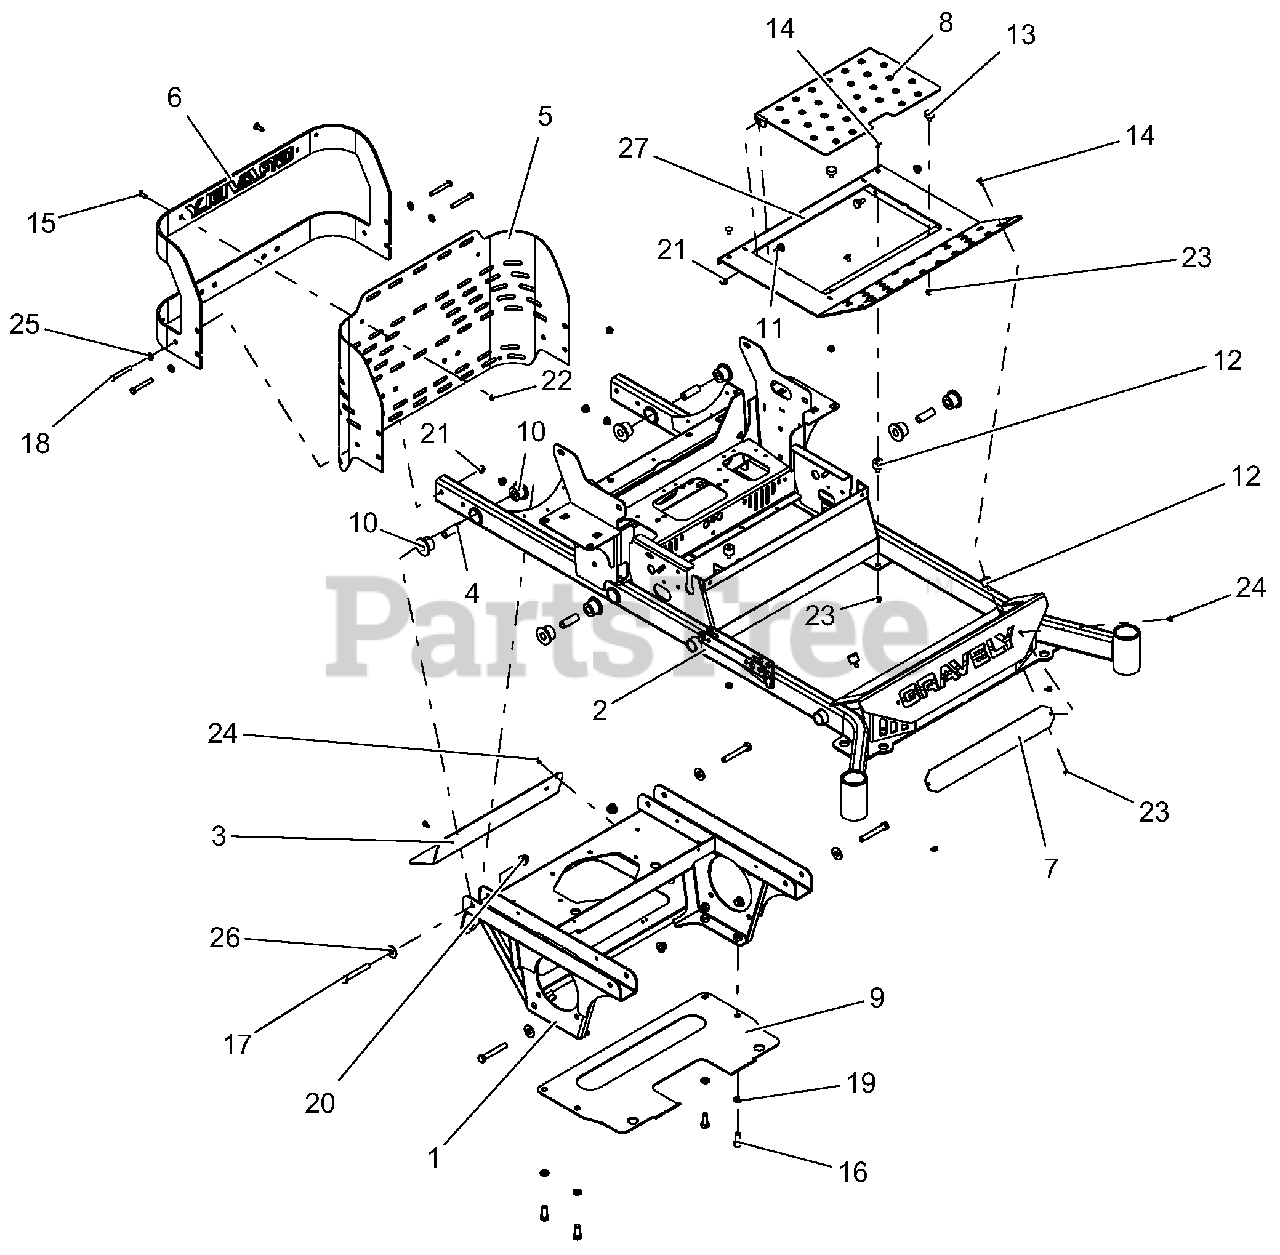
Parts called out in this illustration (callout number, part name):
1	WLDT, 200 PT AXLE/ENGINE FRAME
2	52-66" MAIN FRAME W/SAFETY DECALS
3	SHIELD, MUFFLER HEAT-BLACK
4	SPCR, .50 X .75 X 2.23 YZ
5	GUARD, REAR BUMPER FINGER-BLACK
6	REAR BUMPER W/SAFETY DECALS-GAS
7	PLATE, BUMPER LOGO BACKING-BLACK
8	INSPECTION PANEL W/SAFETY DECAL
9	PLATE-TRANSMISSION SKID-RED
10	BSHG, FLG .75 X 1.51 X 2.00 X .18
11	BLT, SHLDR EP .38-16X.30 HEX YZ
12	BUMPER, STUD MOUNTED W/FEMALE INSERT
13	BUMPER, RUBBER
14	BLT-RDHDSQNK .31-18X.50 G5 YWZC
15	BLT-RDHDSQSHNK .31-18X1.00 G5YWZC
16	BLT-HEX .50-13X1.25 GR5 YWZC
17	BLT-HEX .50-13X3.50 GR5 YWZC
18	BLT-HEX .38-16X2.75 GR5 YWZC
19	WSHR-LK .50X.125 REG YWZC
20	NUT-LK-NYL-FLG .50-13 YWZC
21	NUT-LK-NYL-FLG .38-16 YWZC
22	NUT-LK-NYL-FLG .31-18 YWZC
23	@NUT-SPNLK-FLG .312-18 YWZC
24	SCR-TAP .25-20X.50 HWH TR YWZ
25	WSHR-FL-STL.406X.812X.065 YWZ
26	WSHR-FL-STL.563X1.38X.109YWZC
27	FOOTPLATE WLDMT W/SAFETY DECAL
